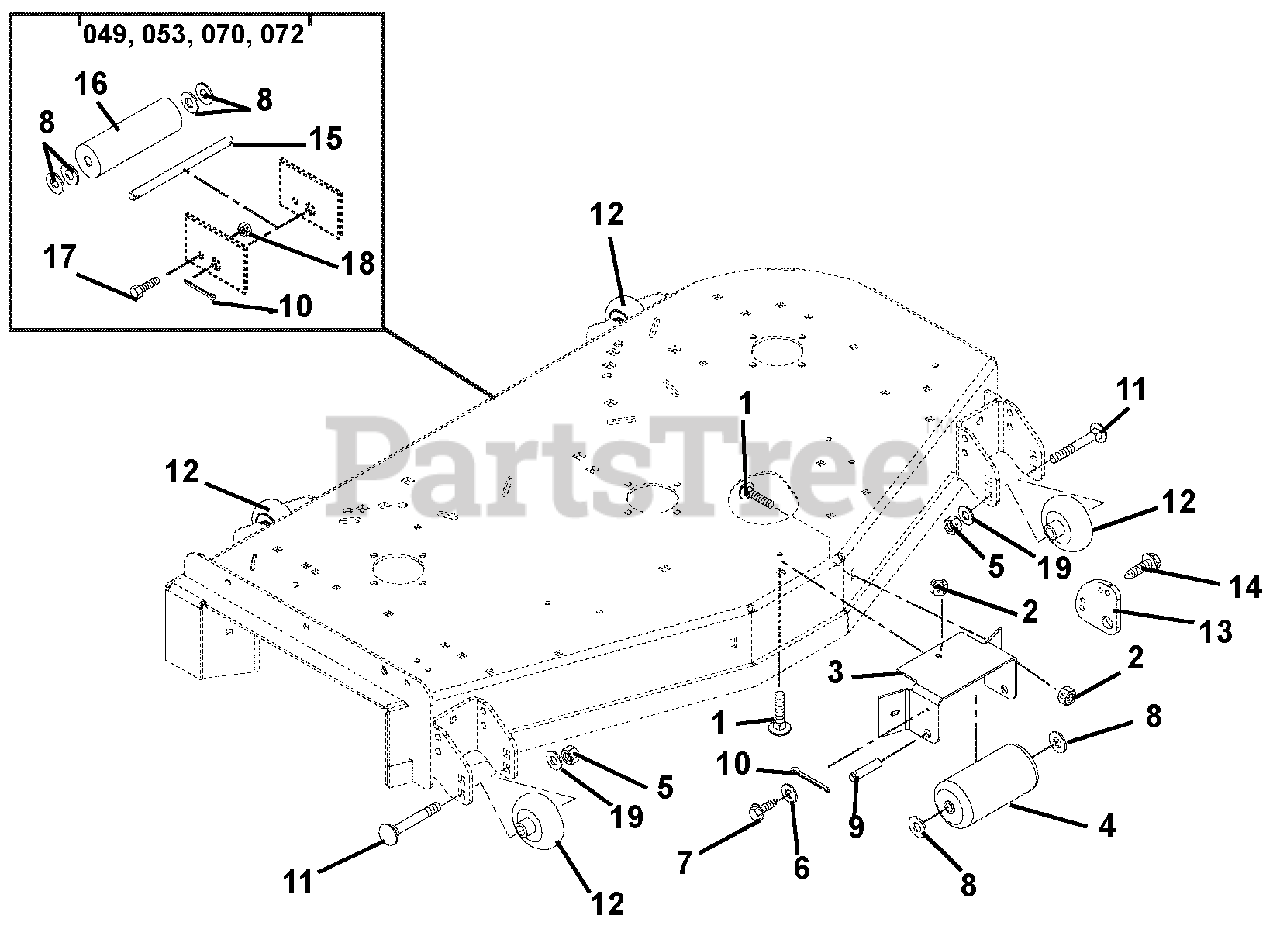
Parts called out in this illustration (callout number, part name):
1	Bolt-Round Head Square Neck .38-16 x 1.00 Grade 5
2	Nut-Locking-Top-Flange .38-16
3	Bracket- Anti-Scalp Roller
5	Nut-Locking-Nylon .50-13
6	Washer-Flat-Steel .281 x .62 x .065
7	Screw-Tapping .25-20 x .75 Hex Washer Head
8	Washer-Flat-Steel .656 x 1.31 x .095 (045, 046, 047, 048, 052, 066, 067 , 068, 069, 071)
10	Pin-Cotter .25 x 2.00 (045, 046, 047, 048, 052, 066, 067 , 068, 069, 072)
11	Bolt-Round Head Square Neck .50-13 x 5.00 Grade 2
12	Wheel, 3 x 5
13	Anti-Scalp Washer
14	Screw-Tapping .25-20 x .62 Hex Washer Head
15	Shift, Center Roller (049, 053, 070, 072)
16	Roller, Gage (049, 053, 070, 072)
17	Bolt-Hex .25-20 x .75 Grade 5 (049, 053, 070, 072)
18	Nut-Locking-Center .25-20 (049, 053, 070, 072)
19	Washer-Flat-Steel .531 x 1.06 x .095
